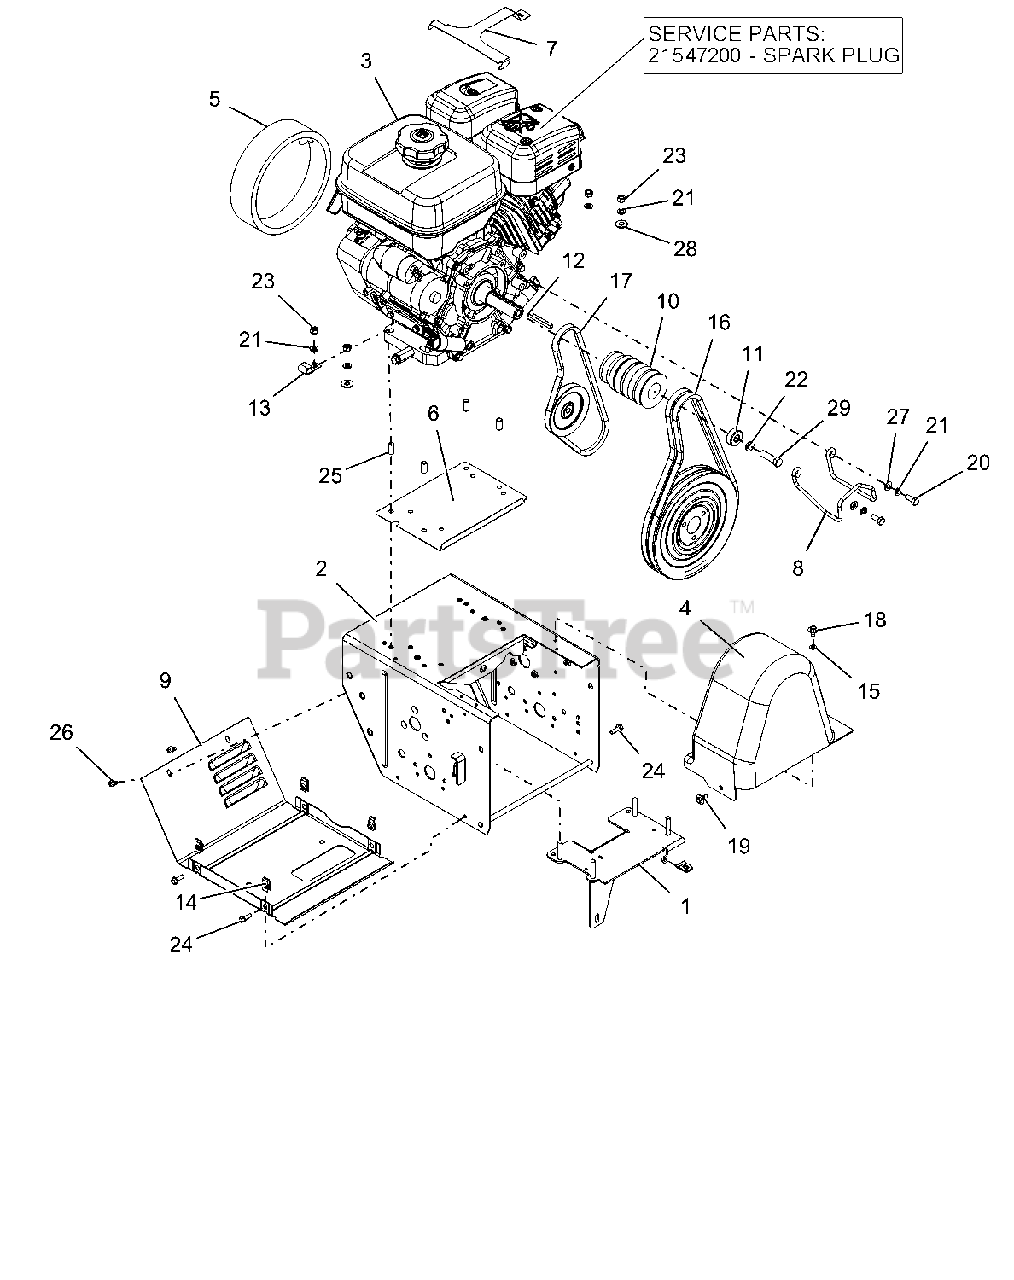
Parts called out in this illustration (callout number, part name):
1	BRKT, HYDRO TRANS LG
2	FRAME, MAIN - PRO SNOW
3	PLUG, SPARK SUBARU
3	ENGINE,SUBARU EX30 AS 12V
4	COVER, BELT-TALL PRO
5	FOAM COVER, RECOIL-SUBARU
6	BAFFLE, WATER-PRO SERIES
7	GUARD, SNOW-SUBARU
8	FINGER, BELT
9	COVER, BOTTOM - VENTILATED
10	SHEAVE, COMBO HYDRO BRUSH
11	BSHG-SPACER .47X1.25X.50
12	KEY .25X.25X2.25
13	J-CLAMP
14	NUT-RTNR .25-20X.56
15	NUT-PUSH .25X.50 O.D.
16	V-BELT, HA-RAW EDGE (SET)
17	V-BELT, 4L-WRAPPED
18	SCR-TAP .25-20X.50 LGHWH TR YZ
19	SCR-TAP .25-20X.5 CAPTIVE
20	BLT-HEX .31-24X.75 YWZC GR5
21	WSHR-LK .312X.097 HVY YWZC
22	@WSHR-LK .44X.109 REG YWZC
23	@NUT-HEX .31-18 YWZC
24	BLT-HEX .25-20X.75 HWH YZ GR5
25	BSHG-SLV .325X.400X.795
26	SCR-TAP .25-20X.50 HWH TR YWZ
27	@WSHR-FL-STL.344X.688X.065YWZC
28	@WSHR-FL-STL.38X.875X.083 YWZC
29	BLT-HEX .44-20X1.50 G5 YZ EP80
